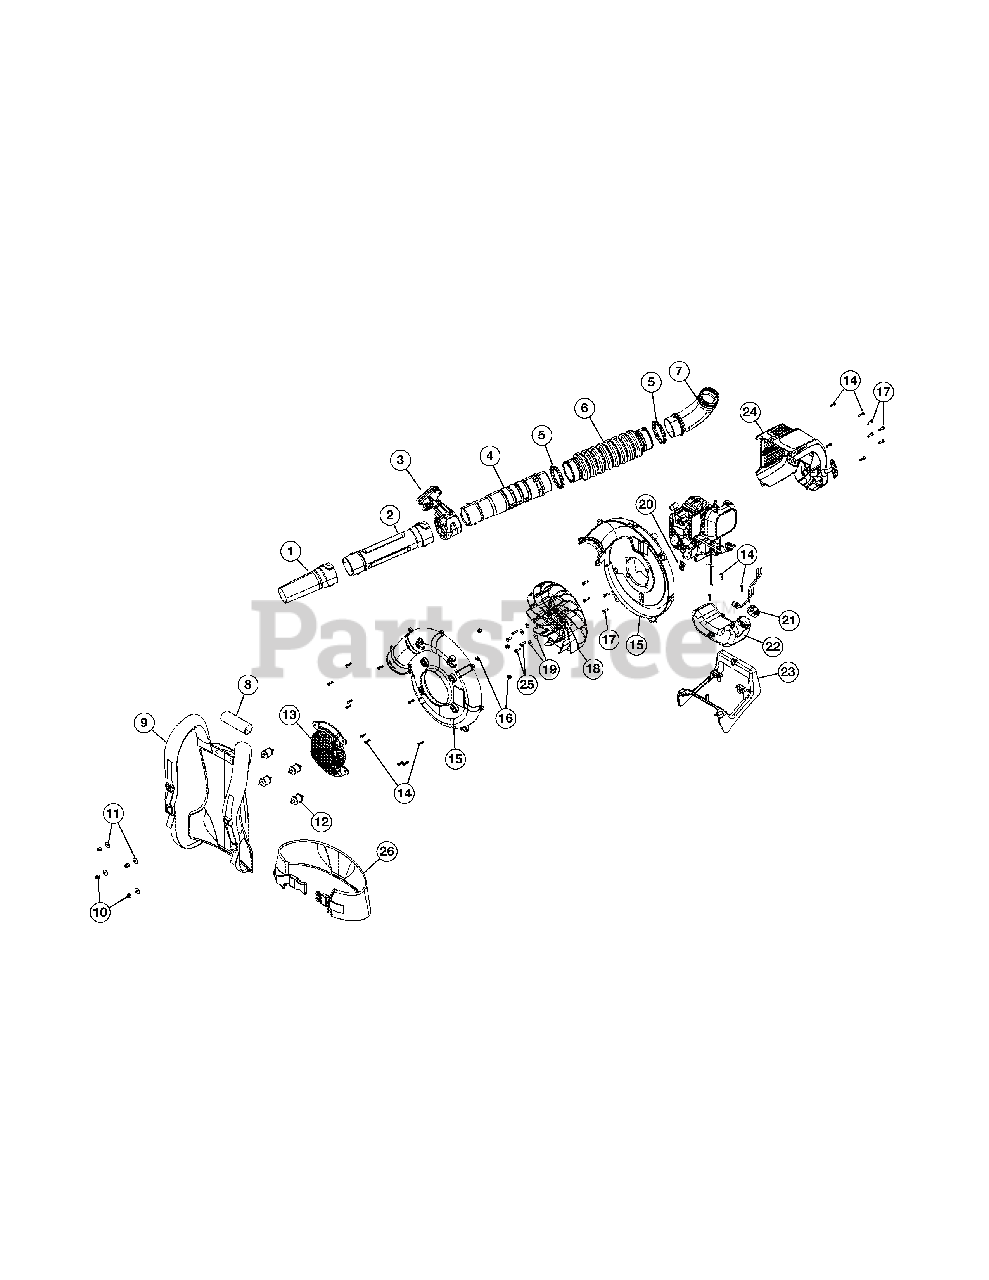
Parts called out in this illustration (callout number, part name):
2	Lower Blower Tube
3	Throttle Grip Assembly
4	Upper Blower Tube
7	Elbow Tube
9	Support System
10	Nut
11	Washer
12	Insulator Mount
13	Intake Cover
15	Impeller Housing Assembly
16	Nut
17	Screw
18	Impeller (includes 19)
20	Throttle Retaining Clip
22	Fuel Tank Assembly (includes 23)
24	Engine Cover Assembly
